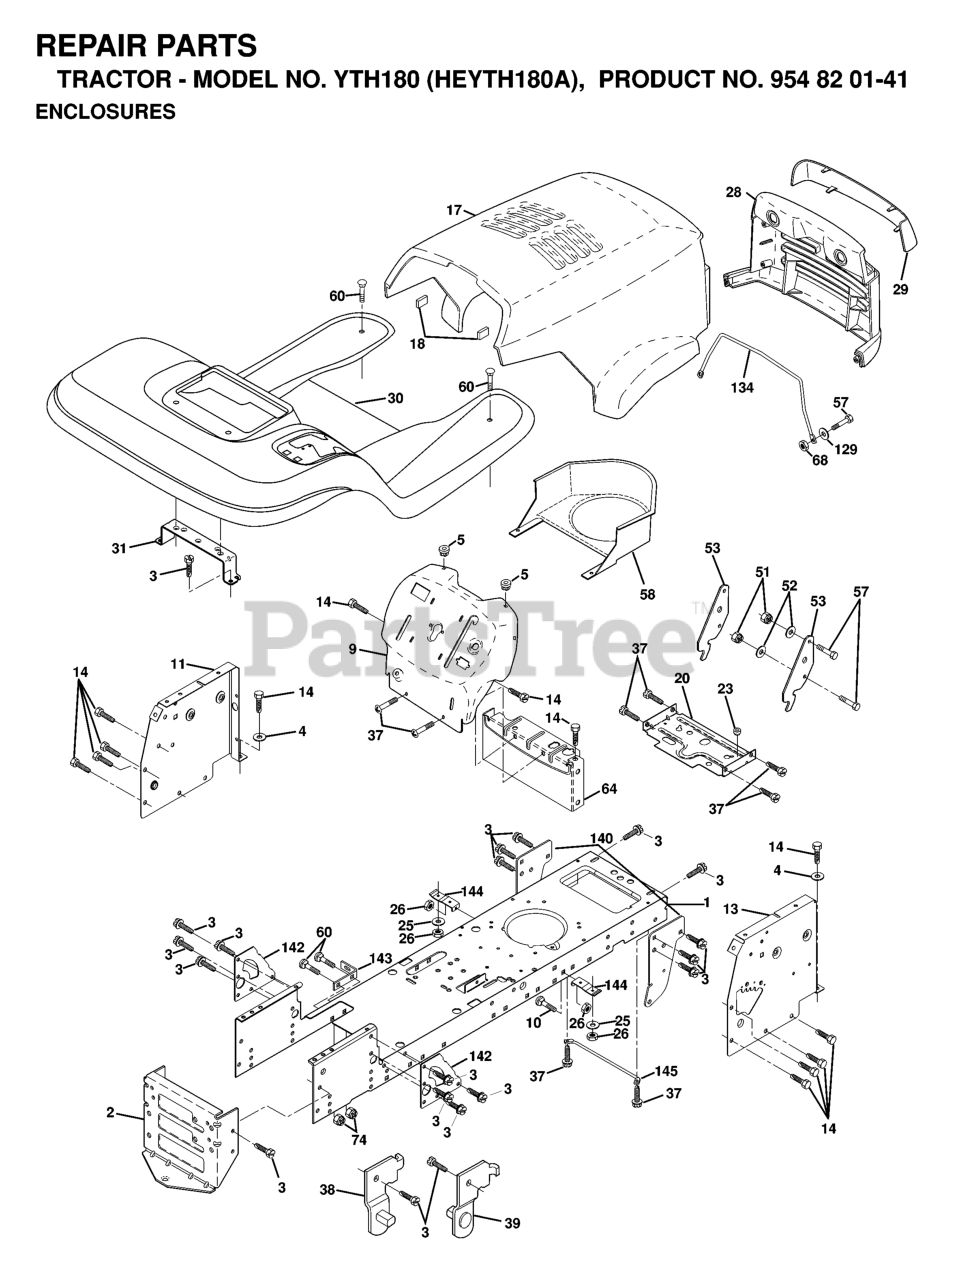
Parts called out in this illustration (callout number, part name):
2	STRETCH DRAWBAR
3	SCREW
4	Washer 13/32 X 3/4 X 16 Ga.
5	BUMPER.RUBBER.HOOD
10	BOLT D
11	PANEL DASH LH
13	DASH PANEL
14	SCREW LT
17	HOOD
18	BUMPER HOOD T
20	PLATE MTG
23	BUSHING.SNAP.NYL.BLK.
25	WASHER
26	NUT
28	GRILL
29	LENS
30	FENDER FOOTREST
31	BRACKET.SUPPORT.FENDER
37	Screw 5/16-18 x 1/2 Hex, Self Tapping 5/16-18 x 1/2
38	BRACKET LH PIVOT
39	BRACKET RH PIVOT
51	LOCKNUT.NYLOC.1/4-20
52	WASHER
53	BRACKET PNT PICK OFF LT/PL
57	BOLT
58	AIR CONDUCTOR
60	Bolt - Rd. Hd. Sq. Neckiage 3/8 16 x 3/4
64	DASH LOWER
68	NUT
129	WASHER
134	ROD SUPPORT HOOD LT/PL HUS.
140	BRACKET SUSPENSION FRONT
142	PLATE
143	BRACKET, SWAY BAR
144	BRACKET FOOTREST
145	ROD PIVOT CHASSIS/HOOD
